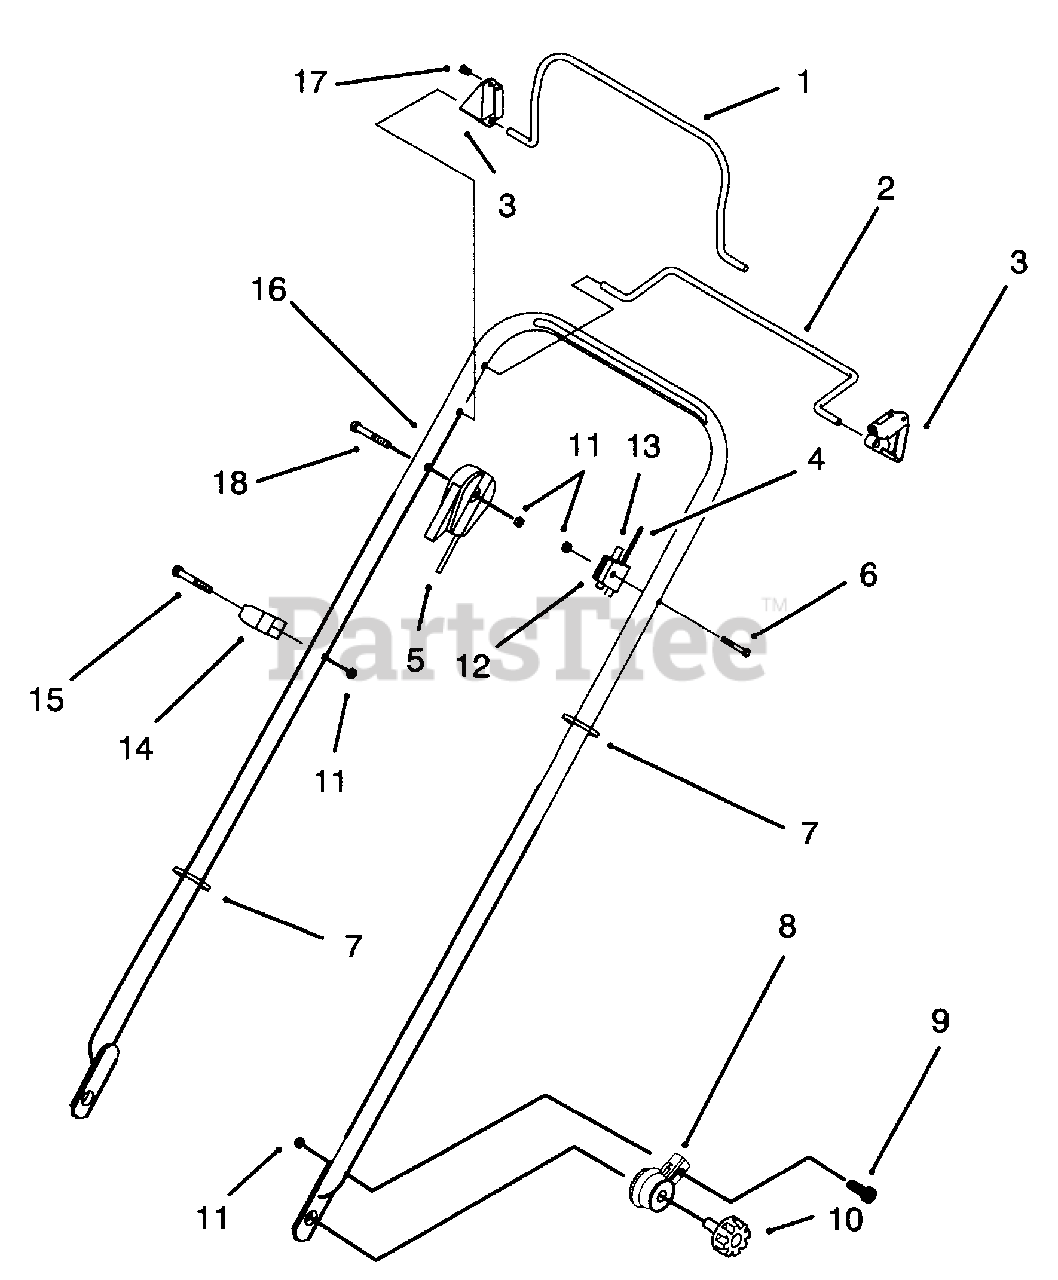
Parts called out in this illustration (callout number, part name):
1	Bail-Brake Int'l
2	Bail-SP Control Int'l
3	Stop-Pivot
4	Cable-Brake
5	Cable-Throttle
6	Screw-Hex Hd. Cap
7	Tie-Cable
8	Handle-Knuckle
9	Screw-Pan Hd.
10	Knob-Handle Mount
11	Nut-Lock
12	Support-Cable
13	Cable-Traction
14	Guide-Rope
15	Screw-Hex Hd. Cap
16	Handle-Int'l
17	Rivet-Pop
18	Screw-Hex Hd. Cap
